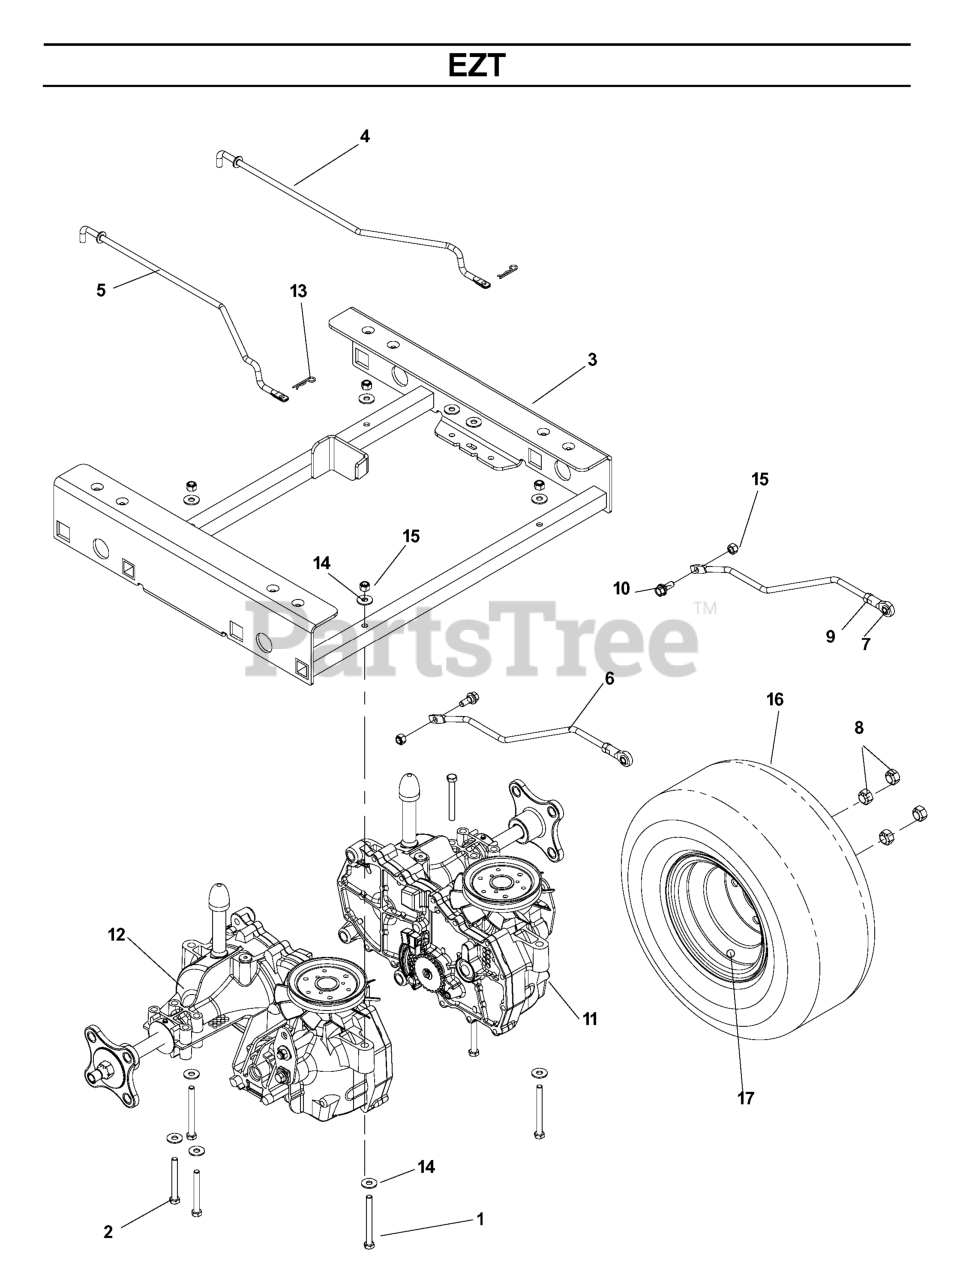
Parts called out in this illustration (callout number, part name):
1	HCS 5/16-18 X 3 1/4
2	HCS 5/16C X 2-3/4
3	SUB FRAME PAINTED
4	BYPASS LINKAGE, LEFT
5	BYPASS LINKAGE, RIGHT
6	MOTION CONTROL ROD ASM
7	BALL JOINT, RIGHT HANDED
8	LUG NUT 1/2F
10	BOLT, SHOULDER
11	HG_EZT, LT
12	HG_EZT RIGHT
13	HAIRPIN #2
14	WASHER 5/16 FLAT
15	NUT 5/16 NYLOC
16	TIRE/WHEEL.ASSEM.18X7.5-8.ZTR
17	VALVE STEM TR-412
